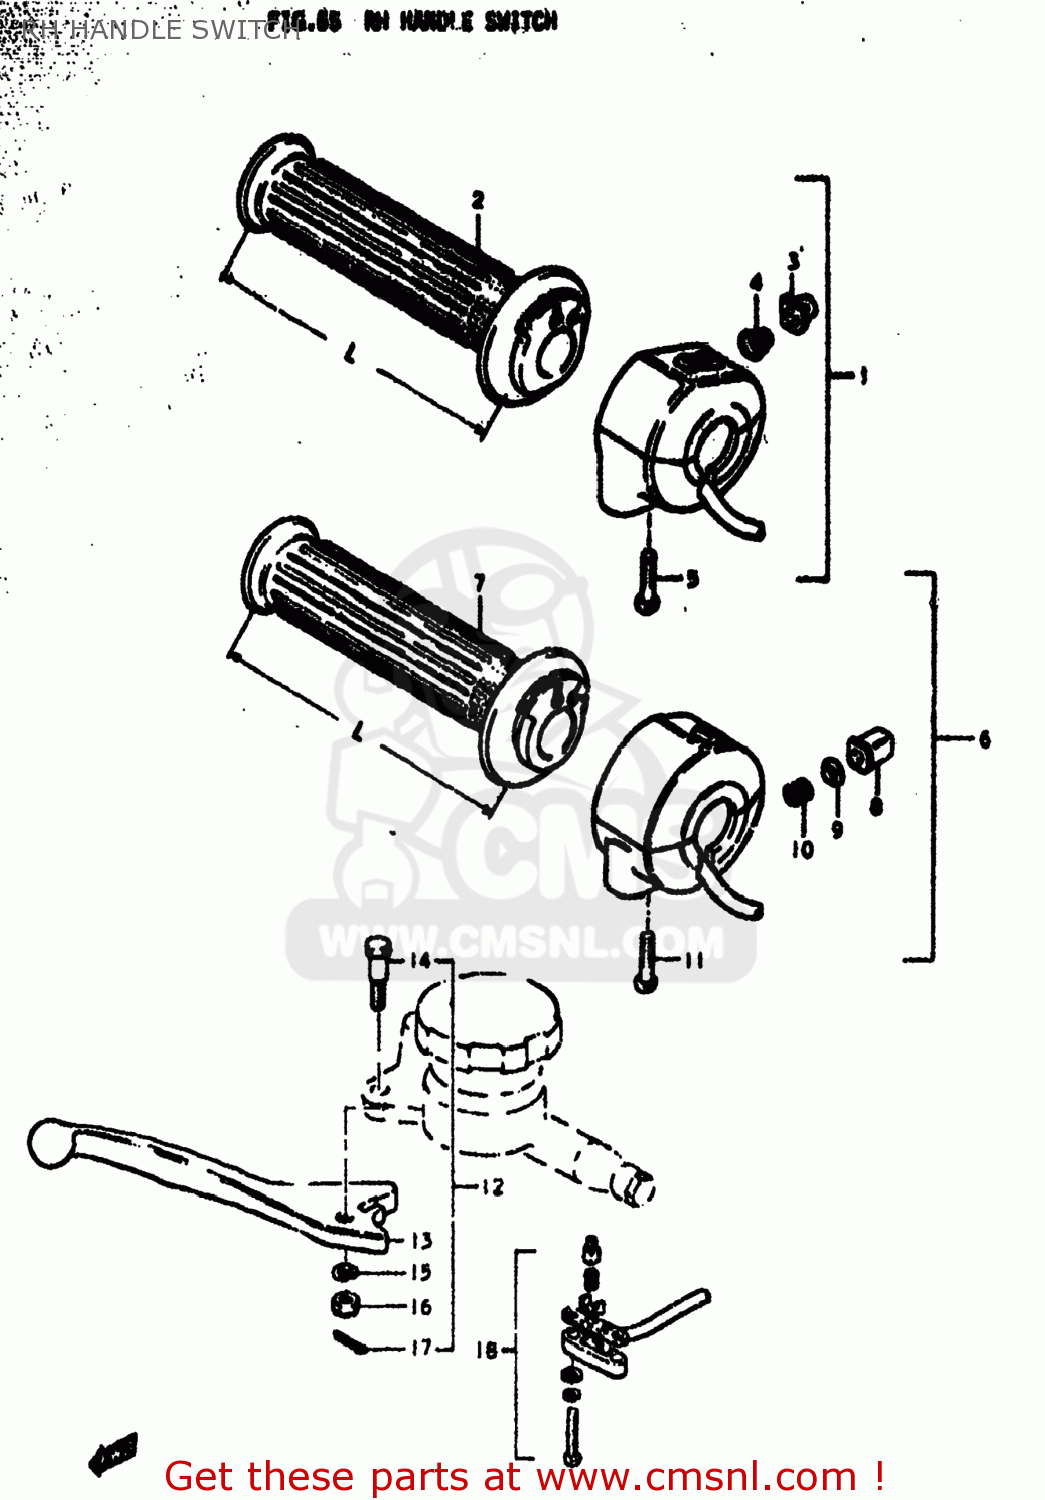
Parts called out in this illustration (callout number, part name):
1	GRIP ASSEMBLY,THROTTLE
2	GRIP,THROTTLE
3	BUTTON
4	SPRING
5	SCREW
6	CASE ASSEMBLY,THROTTLE
7	GRIP,THROTTLE
8	BUTTON,HORN
9	CONTACT
10	SPRING
11	SCREW
12	LEVER ASSEMBLY,BRAKE
13	LEVER,BRAKE
14	BOLT,LEVER
15	LOCK WASHER
16	NUT 6MM
17	COTTER PIN
18	SWITCH ASSY,STOP
